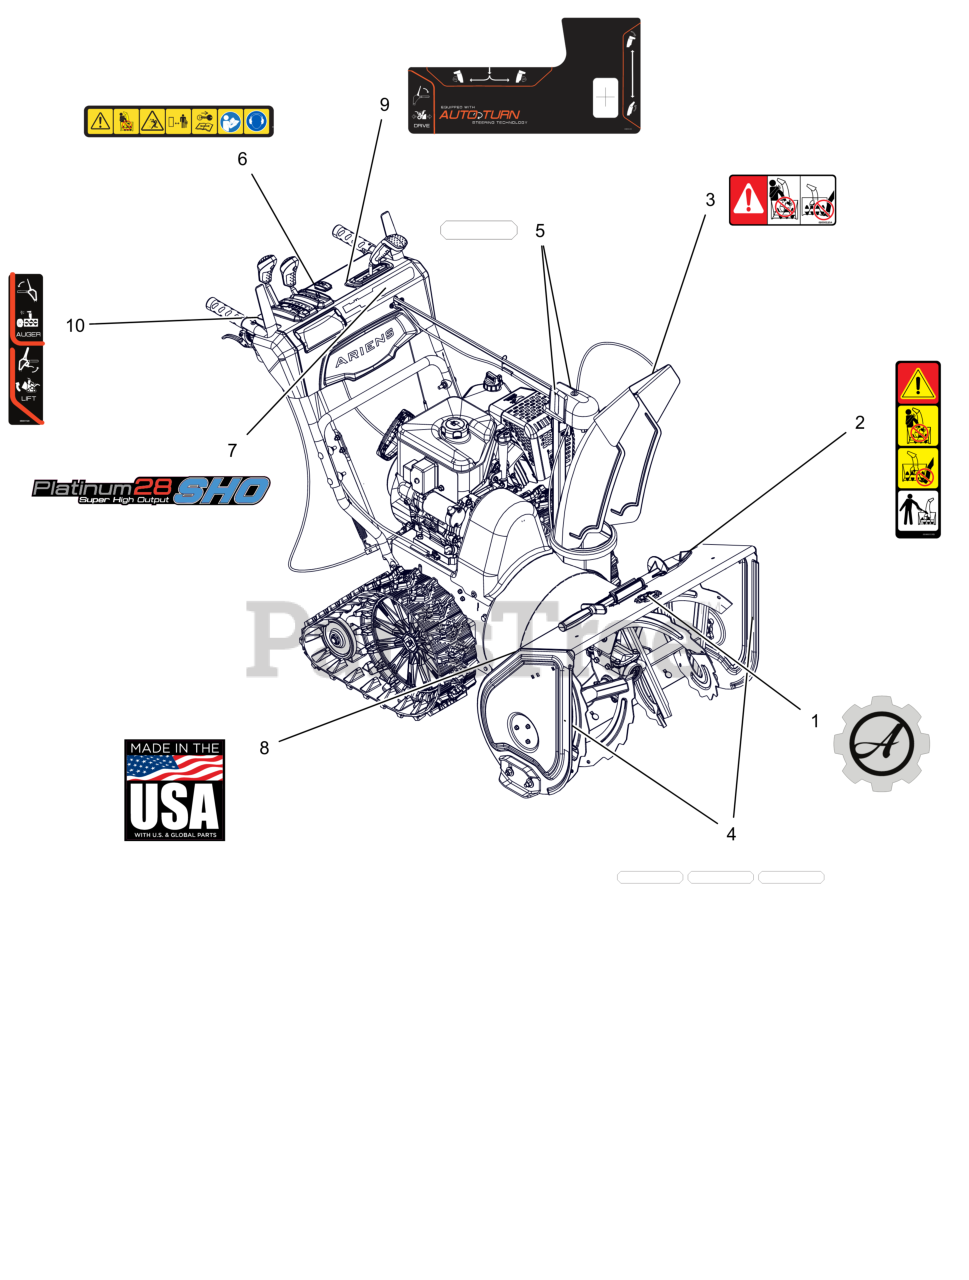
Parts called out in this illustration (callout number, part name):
1	DECAL, ARIENS - GEAR BADGE
2	DECAL, DANGER - ROTATING PARTS
3	DECAL, DANGER
4	DECAL,REFLECTIVE,HOUSING
5	DECAL,REFLECTIVE,GEAR COVER
6	DECAL,DASH - SAFETY
7	DECAL, DASH, PLATINUM 28 SHO
8	DECAL, MADE IN USA
9	DECAL,CONTROL-LG QT2
10	DECAL,CONTROL-RH TRACK
